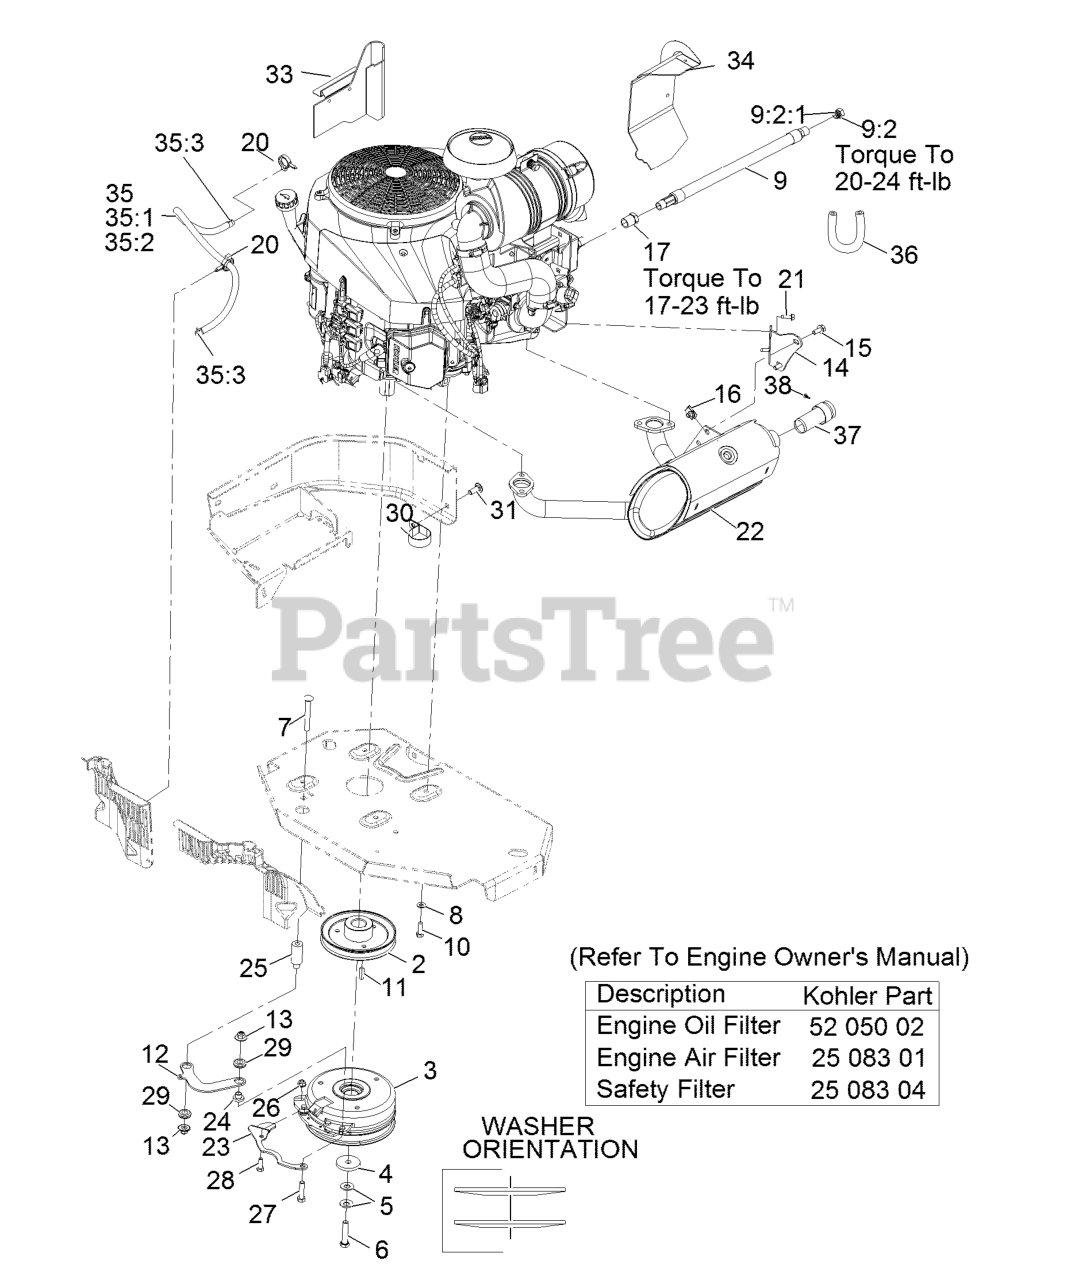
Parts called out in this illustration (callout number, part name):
2	SHEAVE
4	WASHER-CLUTCH
5	WASHER-SPRING
6	SCREW-HH W/LOCTITE
7	SCREW-CARR
8	WASHER-SPRING
9	OIL DRAIN HOSE ASM
9:2	PLUG-HH
9:2:1	O-RING
10	SCREW-HH
12	LINK-ANCHOR, CLUTCH
13	Nut-Nyloc 3/8-16 Flg
14	BRACKET-MUFFLER
15	SCREW-HHF
17	BUSHING
20	CLAMP-HOSE
23	BELT-GUIDE
26	NUT-HF, NI
27	SCREW-HH
28	SCREW-HH
29	GROMMET-RUBBER
30	CLAMP-R
31	SCREW-CARR
33	BAFFLE-RH
35	FUEL LINE ASM
35:1	HOSE-FUEL
35:2	SLEEVE, THERMAL
35:3	CLAMP-HOSE
36	SLEEVE, THERMAL-SHORT
37	ARRESTOR-SPARK
38	SCREW-HWH
